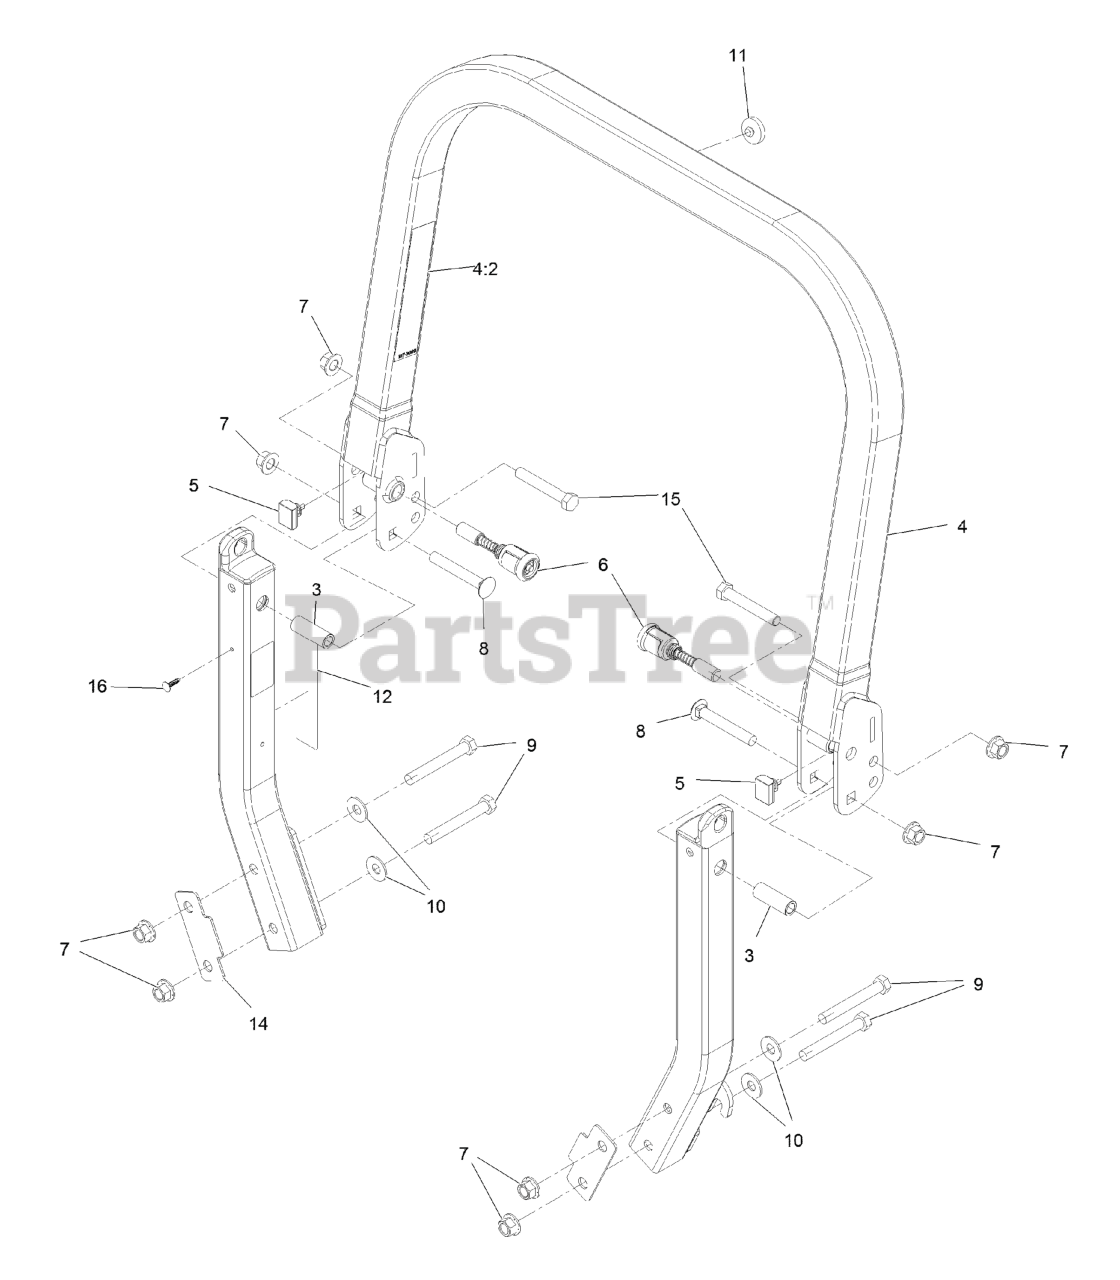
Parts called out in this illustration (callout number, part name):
4	UPPER ROPS ASM
4:2	DECAL-WARNING
5	BUMPER-ROPS
6	PIN-SPRING
7	Nut-Lock 1/2-13
8	SCREW-CARR
9	SCREW-HH
10	WASHER-SPRING
11	BUMPER-PUSH-IN, RUBBER
12	DECAL-CAUTION, FUEL VENT
15	SCREW-HH
16	PLUG-PLASTIC
